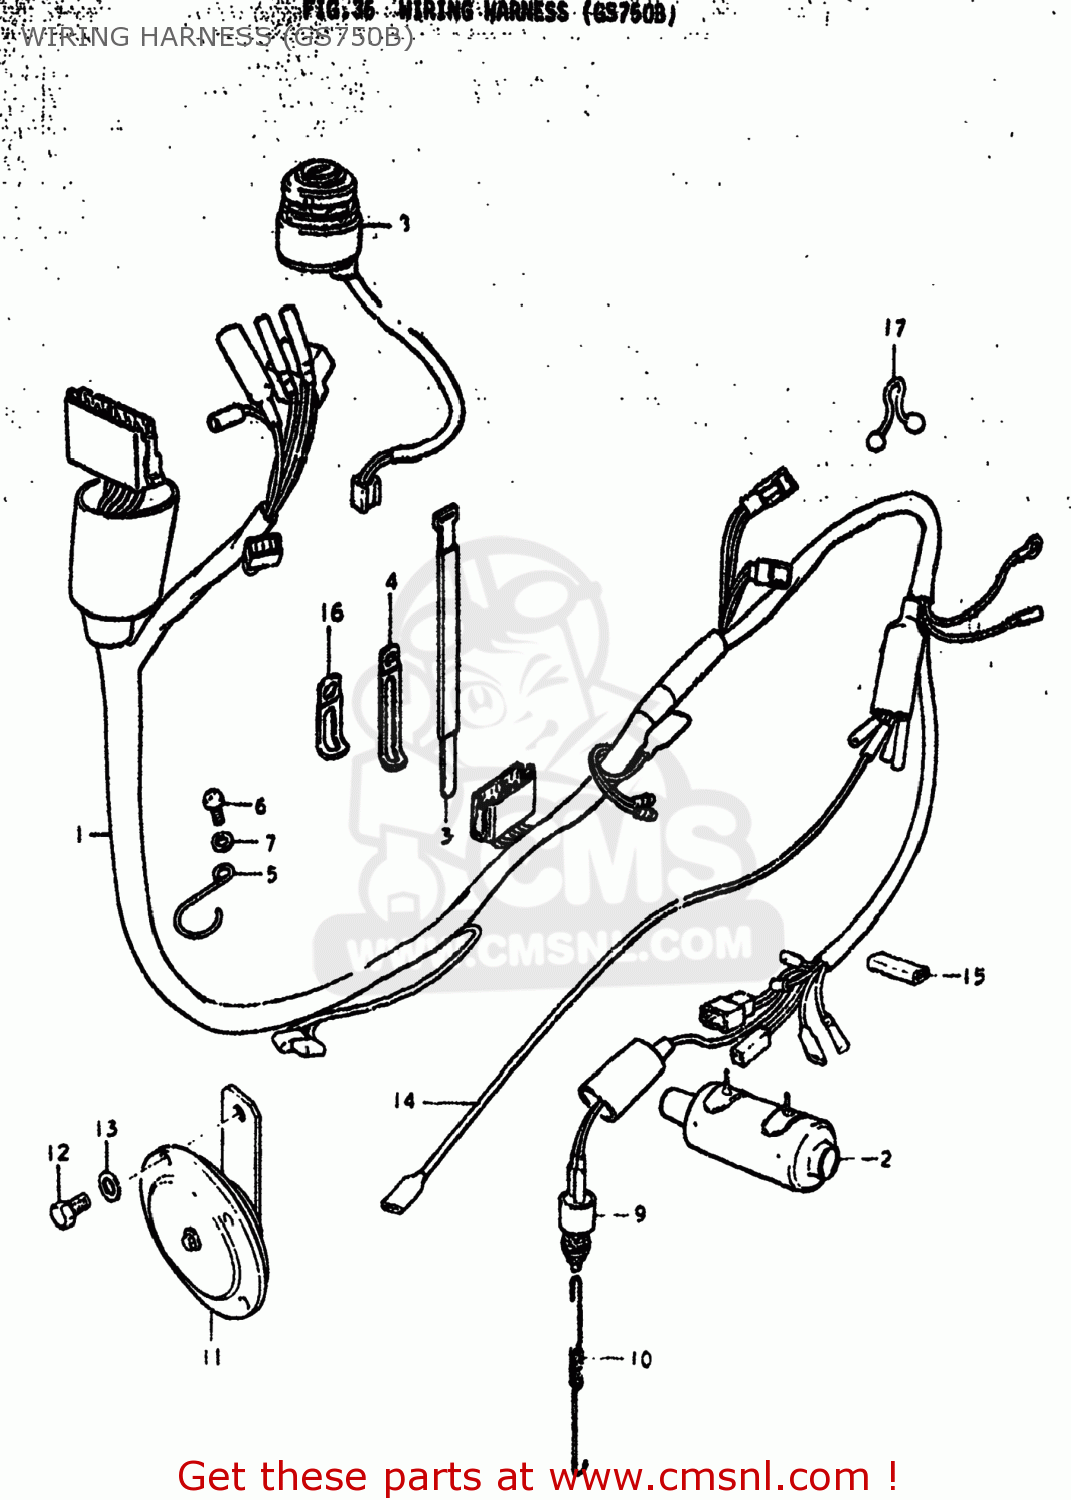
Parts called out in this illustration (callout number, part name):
1	HARNESS,WIRING
2	BOOT,WIRING HARNESS
3	CLAMP
4	CLAMP
5	GUIDE,WIRING HARNESS
6	SCREW 6X12
7	WASHER 6MM
8	SWITCH ASSEMBLY,IGNITION
9	SWITCH ASSY,BRAKE LAMP
10	SPRING
11	HORN ASSY
12	BOLT 8X12
13	WASHER
14	WIRE
15	PROTECTOR,WIRING HARNESS
16	CLAMP
17	CLAMP
